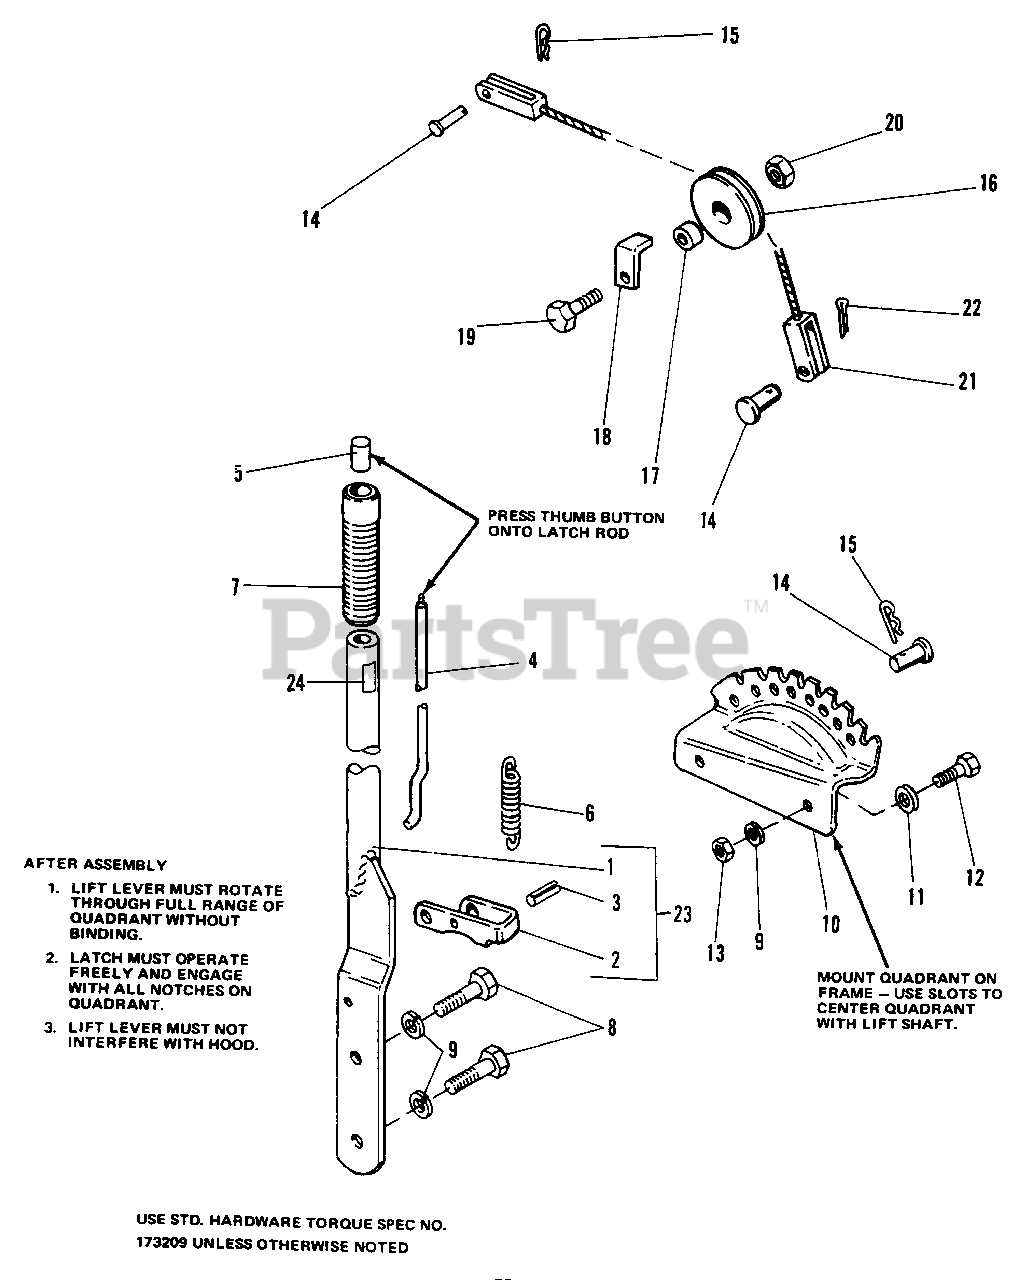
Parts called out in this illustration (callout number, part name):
1	LIFT LEVER ASSEMBLY
2	LATCH, Lift Lever
3	PIN, Spring, 3/8 x 1-1/4
4	ROD, Latch
7	GRIP
8	CAPSCREW, Hex Hd.,3/8-16 x 1
9	LOCKWASHER, 3/8
11	WASHER, 5/16
12	CAPSCREW, Hex Hd., 3/8-16 x 3/4
13	NUT, Hex, Full, 3/8-16
15	CLIP, Spring
18	GUARD, Cable
19	SCREW, Special
20	LOCKNUT, Hex, Jam, 3/16
21	LIFT CABLE ASSY
22	PIN, Cotter. 3/32 x 7/8
23	LIFT LEVER SUB ASSY.
24	DECAL Lift Lever
